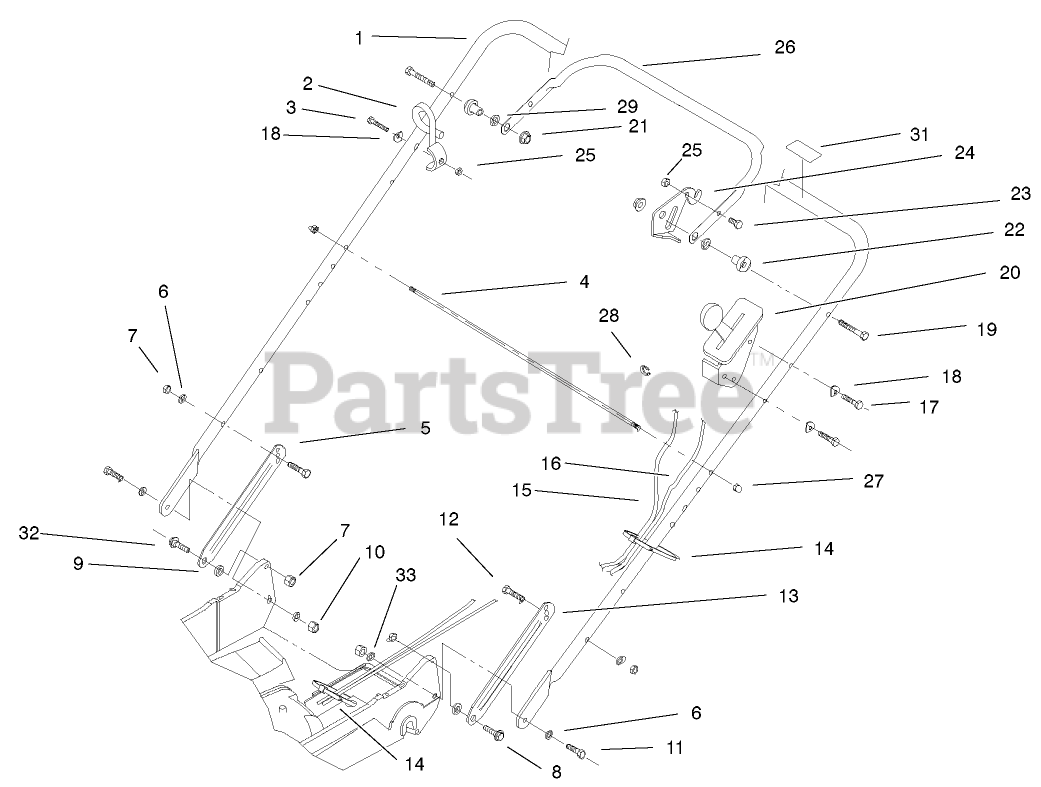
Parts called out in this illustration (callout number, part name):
2	GUIDE-ROPE
3	SCREW-HH
4	ROD-SUPPORT, BAG
5	LATCH-HANDLE, RH
6	WASHER-BELLEVILLE
7	NUT-LOCK, NI
8	SCREW-SHOULDER
9	SPACER
10	NUT-LOCK, NI
11	SCREW-HH
12	SCREW-HH
13	LATCH-HANDLE, LH
14	TIE-CABLE
15	CABLE-BRAKE
17	SCREW-HH
18	WASHER
19	SCREW-HH
20	CONTROL-THROTTLE
21	NUT-LOCK, NI
22	SPACER-SUPPORT
23	SCREW-HH
24	LEVER-CONTROL
25	NUT-LOCK, NI
26	BAR-CONTROL
27	NUT-CAP
28	E-RING
29	SPACER-NYLON
31	DECAL-PROTECTION, EAR
32	SCREW-SHOULDER
33	WASHER-PLAIN
